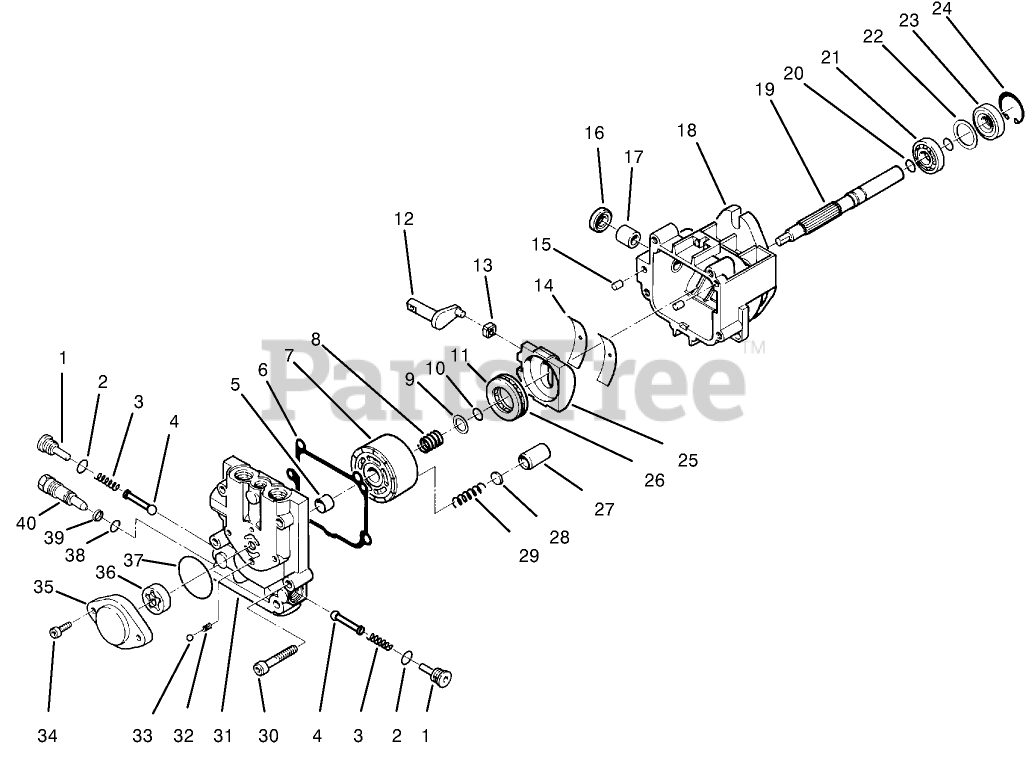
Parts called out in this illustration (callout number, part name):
1	Check Valve Kit (Incl. Ref. #2-4)
2	Seal-O-Ring
4	Poppet
5	Journal-Bearing
6	Gasket-End Cap
9	Washer
11	Plate-Thrust
12	Arm-Trunnion
13	Guide-Slot
14	Cradle-Bearing
16	Seal-Lip
17	Journal-Bearing
19	Shaft
21	Bearing-Ball
23	Seal-Lip
25	Swashplate Assembly
26	Roller-Thrust
29	Spring-Piston
32	Ball
35	Housing-Charge Pump
36	Gerotor Assembly
37	Seal-O-Ring
38	Seal-O-Ring
39	Ring-Back-Up
40	Valve-Bypass
